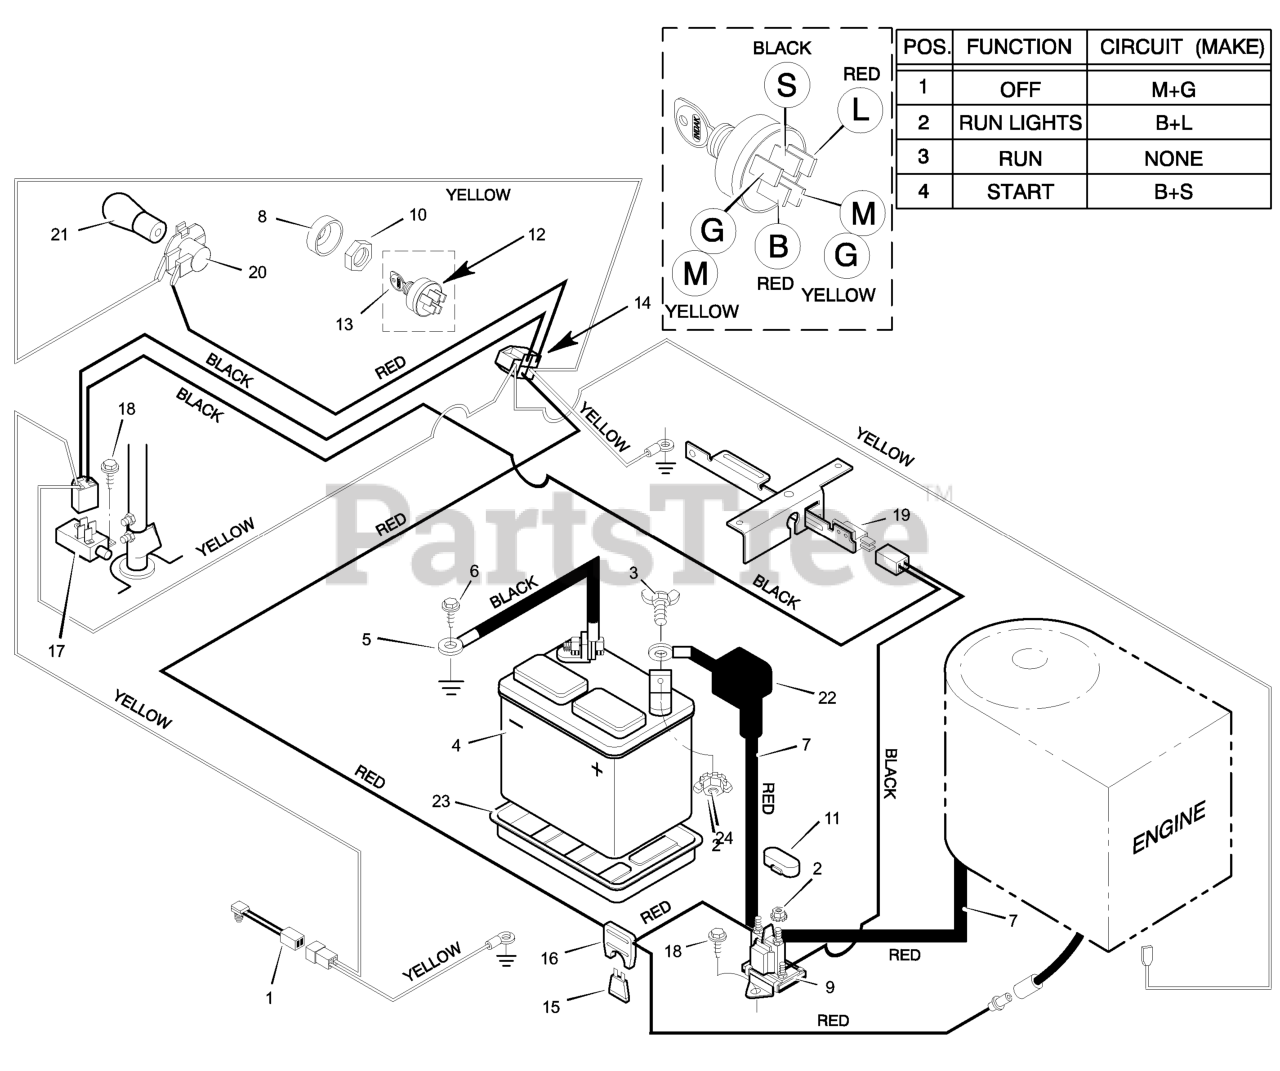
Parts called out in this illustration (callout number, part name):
1	Switch, Seat Sensor
2	Locknut
4	Battery
5	Cable, Battery Ground
7	Cable, Red Battery
8	Cap, Ignition
9	Solenoid
10	Nut, Hex
11	Cover, Solenoid
12	Switch, Ignition
13	Key, Ignition
14	Harness, Chassis Wire
16	Holder, Fuse
17	Switch, Limit
19	Switch, Limit
20	Socket, Light
21	Bulb, Light
22	Cover, Terminal
23	Tray, Battery
24	Wingnut
